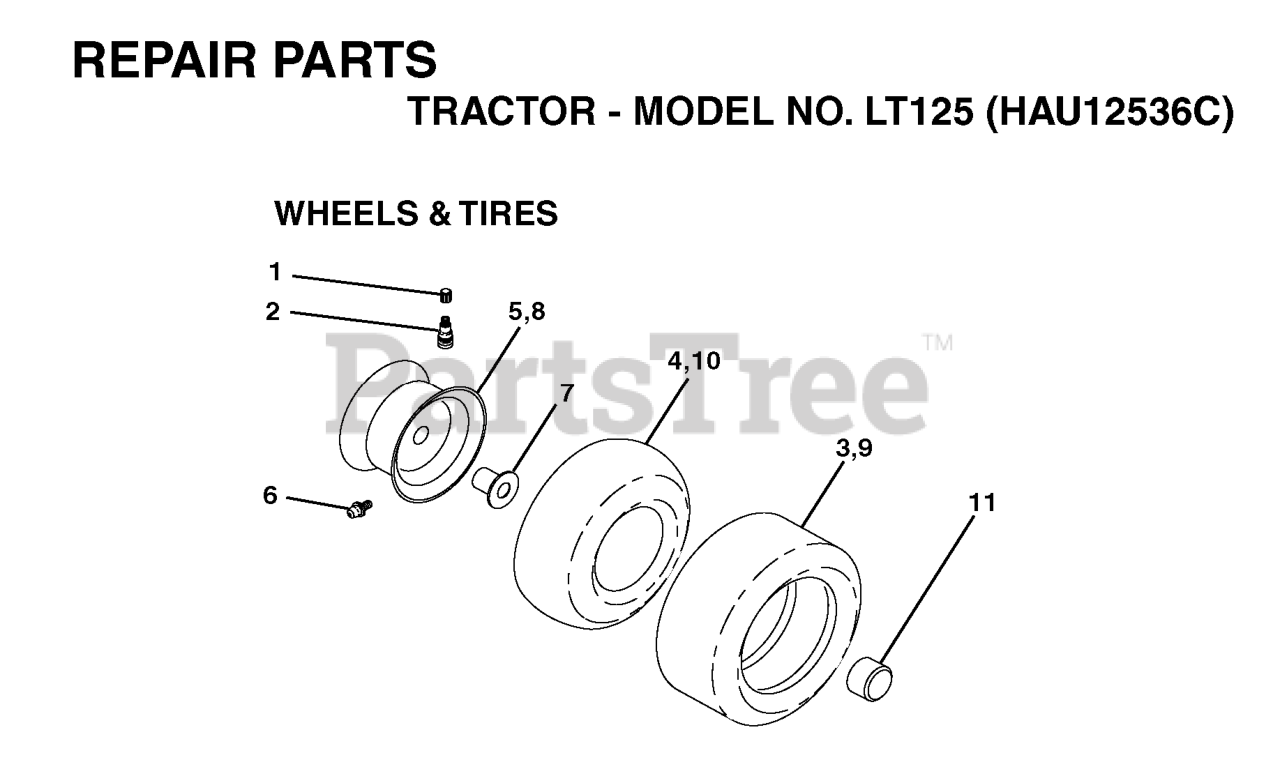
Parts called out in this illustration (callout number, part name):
2	VALVE STEM LT
3	TIRE HEAVY DUTY
4	TUBE.5.3/4.5/6
5	RIM ASM 6" FRONT SILVER
6	FITTING LT
7	BEARING T
8	RIM ASM 8" REAR SILVER
9	TIRE
10	TUBE
11	CAP, AXLE BLK
